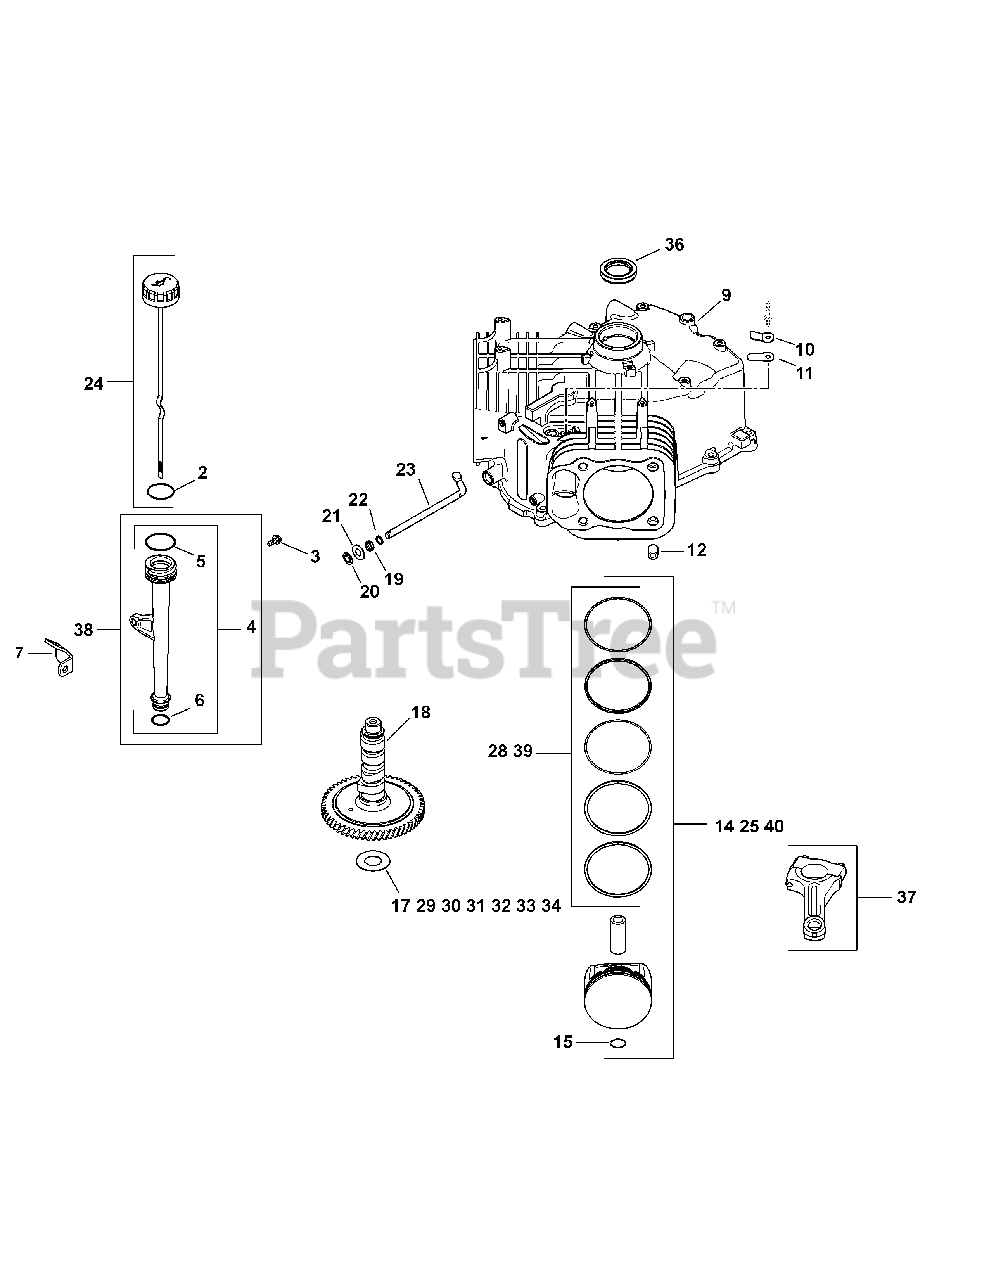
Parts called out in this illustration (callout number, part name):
2	Dipstick Assembly (Cub Yellow)
3	Flg. Thd. Frm. Screw, M5 x 0.8 x 13
7	Oil Fill Tube Bracket
10	Breather Reed Retainer
11	Breather Reed
14	Piston Kit w/ Ring Set
15	Piston Pin Retainer
17	Camshaft Shim (White .028")
18	Camshaft Kit
19	Governor Cross Shaft Seal
20	Ring Retainer
21	Flat Washer, 9mm
22	Flat Washer, 11.32
23	Governor Cross Shaft
24	Dipstick Assembly
25	Piston Kit w/ Ring Set (0.25) 83mm
28	Ring Set (.25)
29	Camshaft Shim (Blue .03")
30	Camshaft Shim (Red .032")
31	Camshaft Shim (Yellow .034")
32	Camshaft Shim (Green .036")
33	Camshaft Shim (Gray .038")
34	Camshaft Shim (Black .04")
36	Oil Seal (Helix Lip)
37	Connecting Rod
38	Tube Assembly
40	Use KH-24-874-27-S Kit
